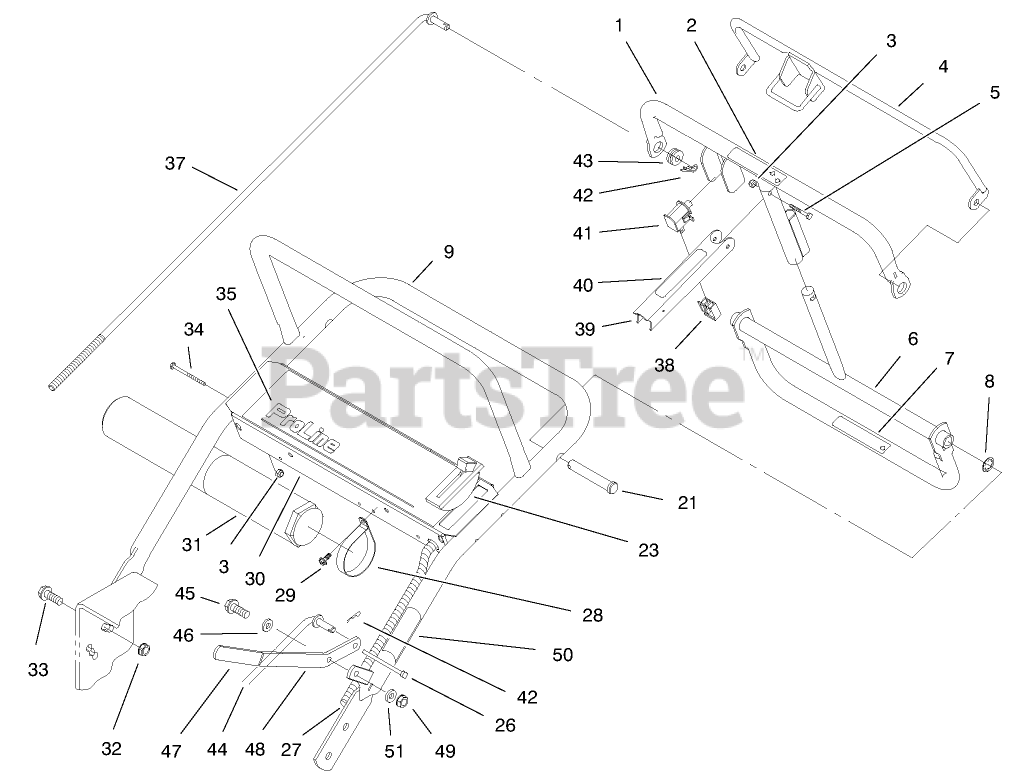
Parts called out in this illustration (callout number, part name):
1	Control Bar
2	DECAL
3	NUT-LOCK, NI
4	Bail ASM
5	SCREW-SHH
6	Pivot-Control
7	DECAL
8	NUT-PUSH-ON, CIRCULAR
9	Upper Handle ASM
21	PIN-CLEVIS
23	Throttle Control
26	TIE-CABLE
27	Wire Harness-Kawasaki
28	CLAMP-R
29	SCREW-HWHTF
30	Panel-Control
31	TUBE-MANUAL
32	NUT-HF
33	SCREW-HHF
34	SCREW-SHH
35	Decal-Panel
37	Rod-Control
38	CONNECTOR-BODY
39	Lever-Parking Brake
40	Decal-Parking Brake
41	SWITCH
42	PIN-COTTER
43	GROMMET-RUBBER
44	Linkage-Blade Drive
45	SCREW-SHOULDER, HWH
46	WASHER-THRUST
47	Grip
48	Lever-Blade Engagement
49	NUT-HEX
50	Decal-Blade Engagement
51	WASHER-FLAT
